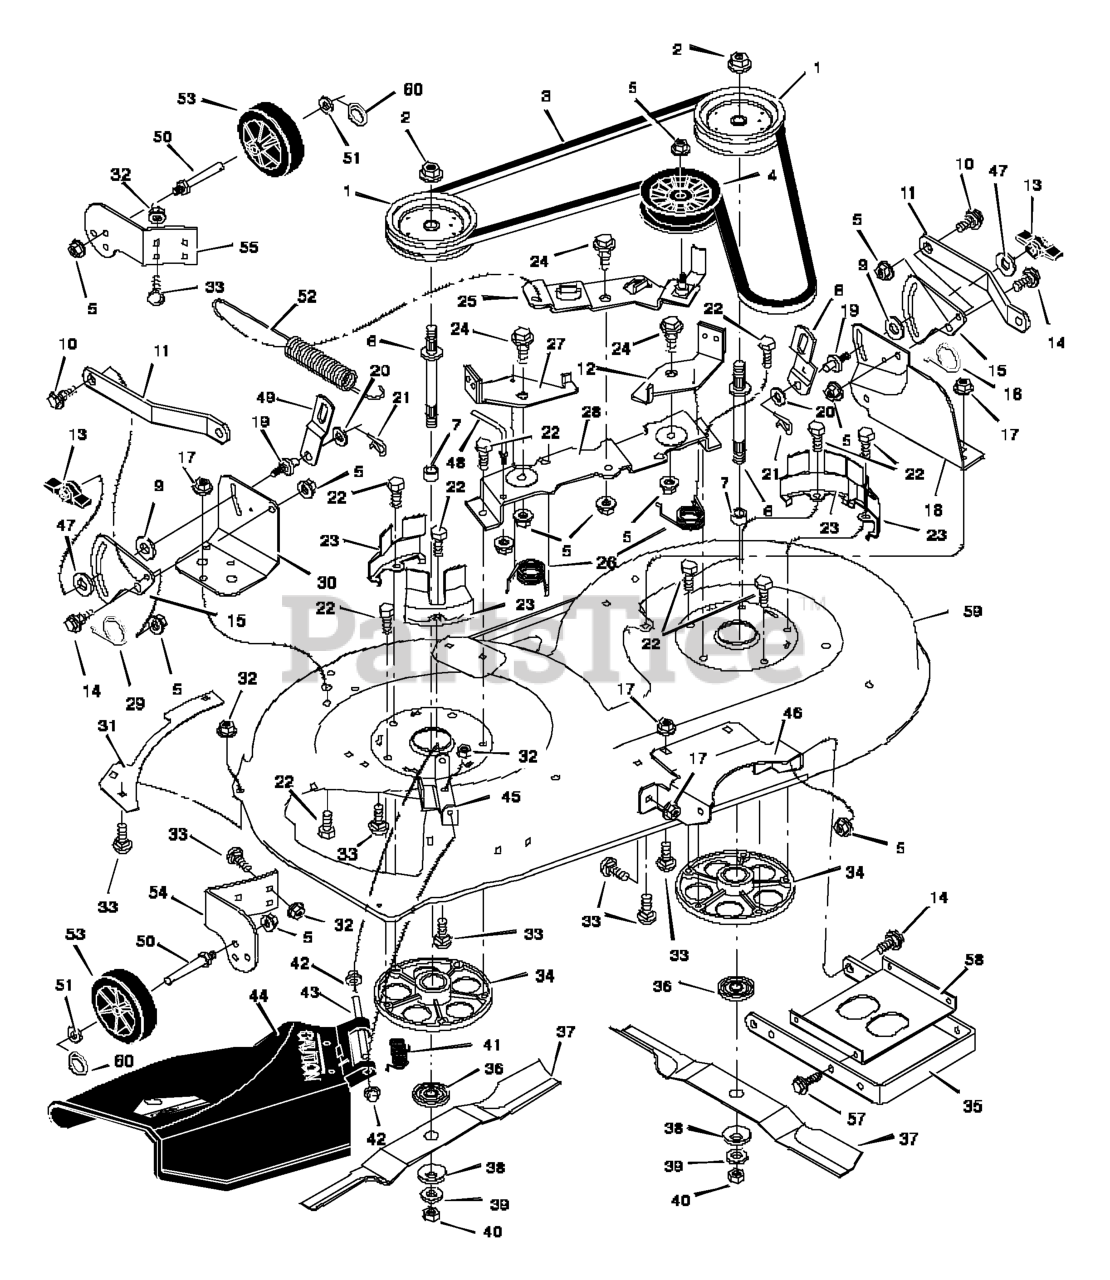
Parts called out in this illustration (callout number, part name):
1	Pulley, Jackshaft
2	Nut, Hex
3	Belt, Mower Drive
4	Pulley, Idler
5	Nut, Flange
6	Jackshaft
8	Link, Left Lift
9	Pad, Friction
10	Bolt, Shoulder
11	Bracket, Suspension
12	Pad Assembly, Left Brake
13	Knob
14	Bolt, Shoulder
15	Plate, Suspension
17	Nut, Flange
18	Bracket, Suspension
19	Pin, Hanger
21	Pin, Hair
22	Bolt
23	Cover, Pulley
24	Bolt, Shoulder
25	Arm, Idler
27	Pad Assembly, Right Brake
28	Bracket, Brake
30	Bracket, Suspension
32	Nut, Flange
33	Bolt, Carriage
34	Mandrell Housing
35	Bracket, Suspension
36	Adapter, Blade
42	Cap, Push On
43	Rod, Pivot
44	Deflector
45	Bracket, Deflector Hinge
46	Bracket, Front Hanger
48	Guide, Belt
49	Link, Right Lift
50	BOLT, Gauge Wheel
52	Spring, Extension
53	Wheel, Gauge
54	Bracket, Right Wheel
55	Bracket, Left Wheel
56	Brace, Hanger
58	Stiffener
59	Housing, Blade
60	Ring, Locking
